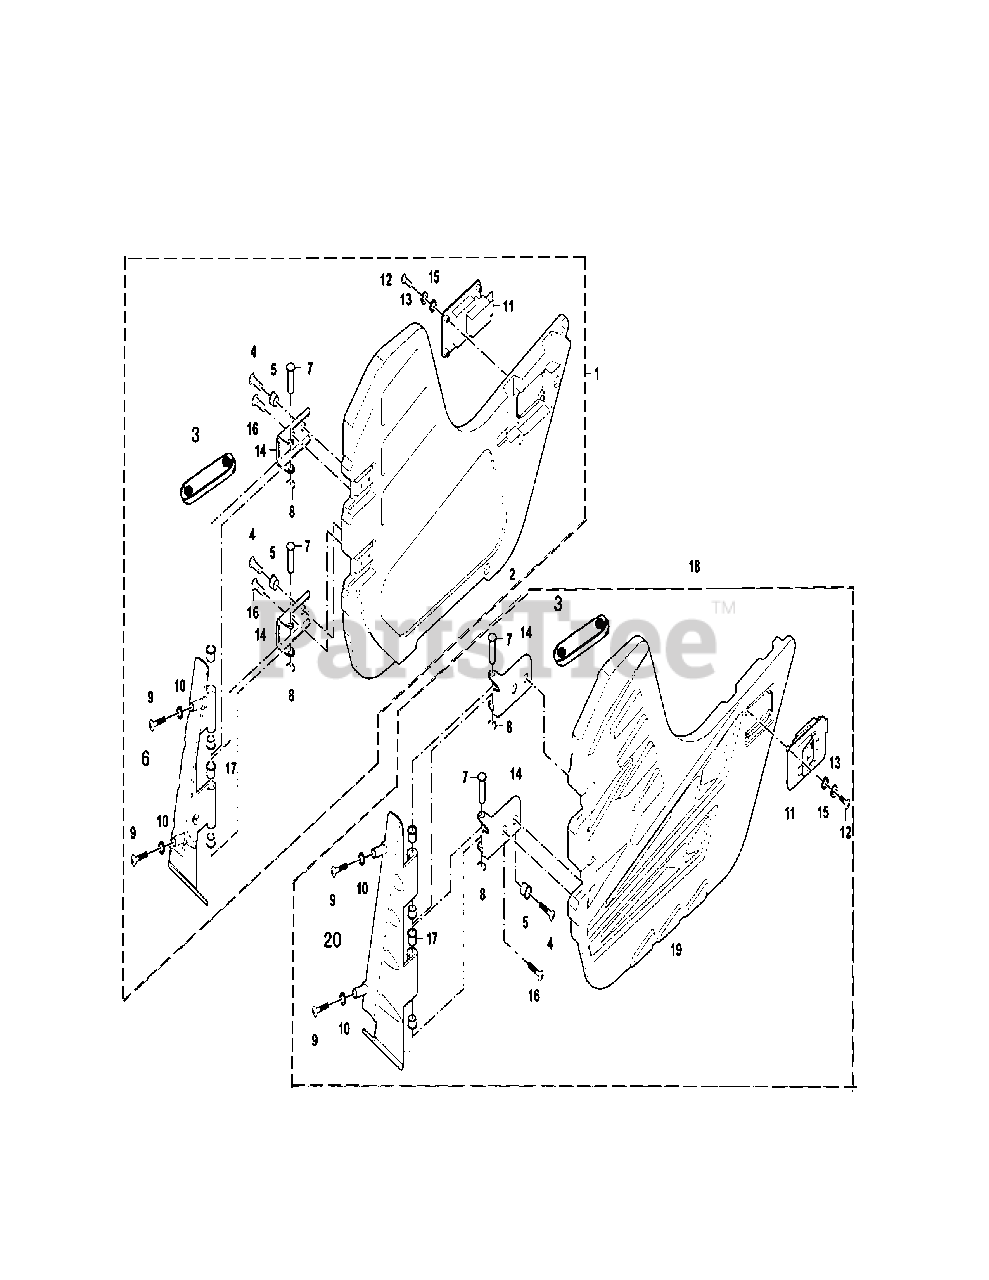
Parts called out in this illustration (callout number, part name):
1	Right Door Comp.
2	Right Door
3	Position Return Band III
4	Cross large plate head screw M6x16
5	Bushing 6.5x9x22x6.5
6	Right Door Mounting Bracket
7	Pin 10x17x44
8	Split Washer 8x1
9	Hexagon Socket Head Bolt M8x22-10x16
10	Curved Washer
11	Right Side Door Locker
13	Spring Gasket-5
14	Side Door Gemel
15	Washer5x12x1
16	Cross Large Plate Head Screw M6x12
17	Nylon Bushing IV
18	Left Door Comp.
19	Left Door
20	Left Door Mounting Bracket
